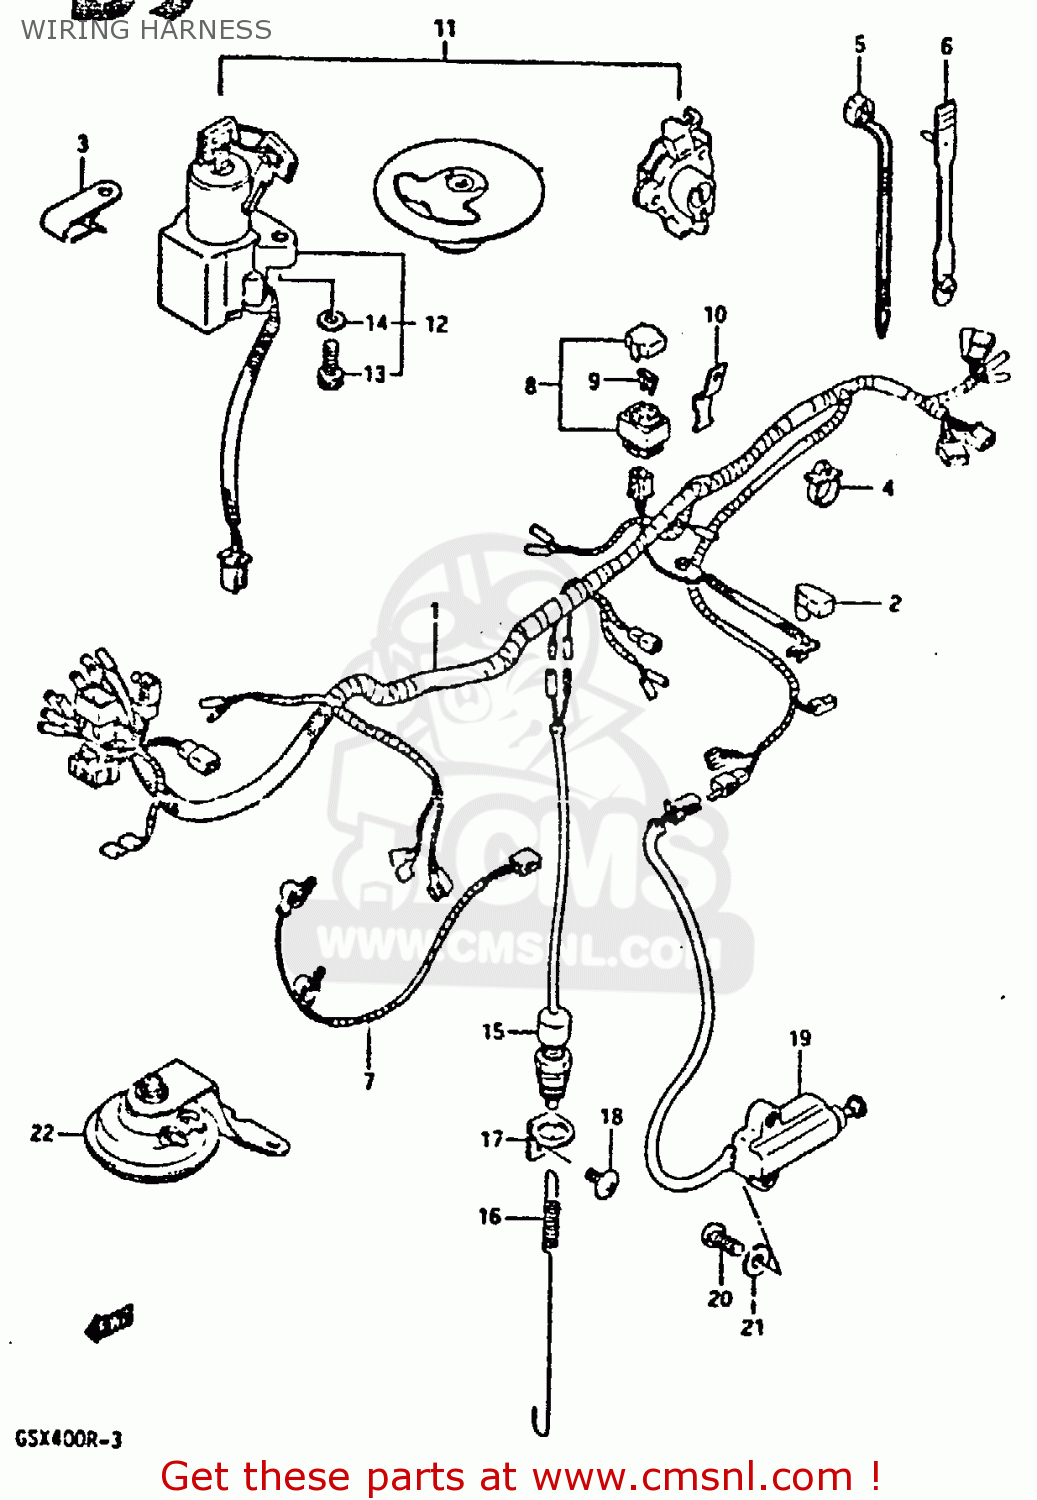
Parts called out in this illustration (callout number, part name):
2	CAP,BATTERY PLUS
3	CLAMP,HANDLE SWITCH
4	CLAMP
5	CLAMP(L:125)
6	CLAMP,L:88
8	BOX ASSEMBLY,FUSE
9	FUSE(20A)
11	LOCK SET
12	SWITCH ASSY.IGN
13	BOLT
14	WASHER,LOCK
15	SWITCH ASSY,STOP LAMP
16	SPRING
18	SCREW 5X10
20	SCREW
21	WASHER
